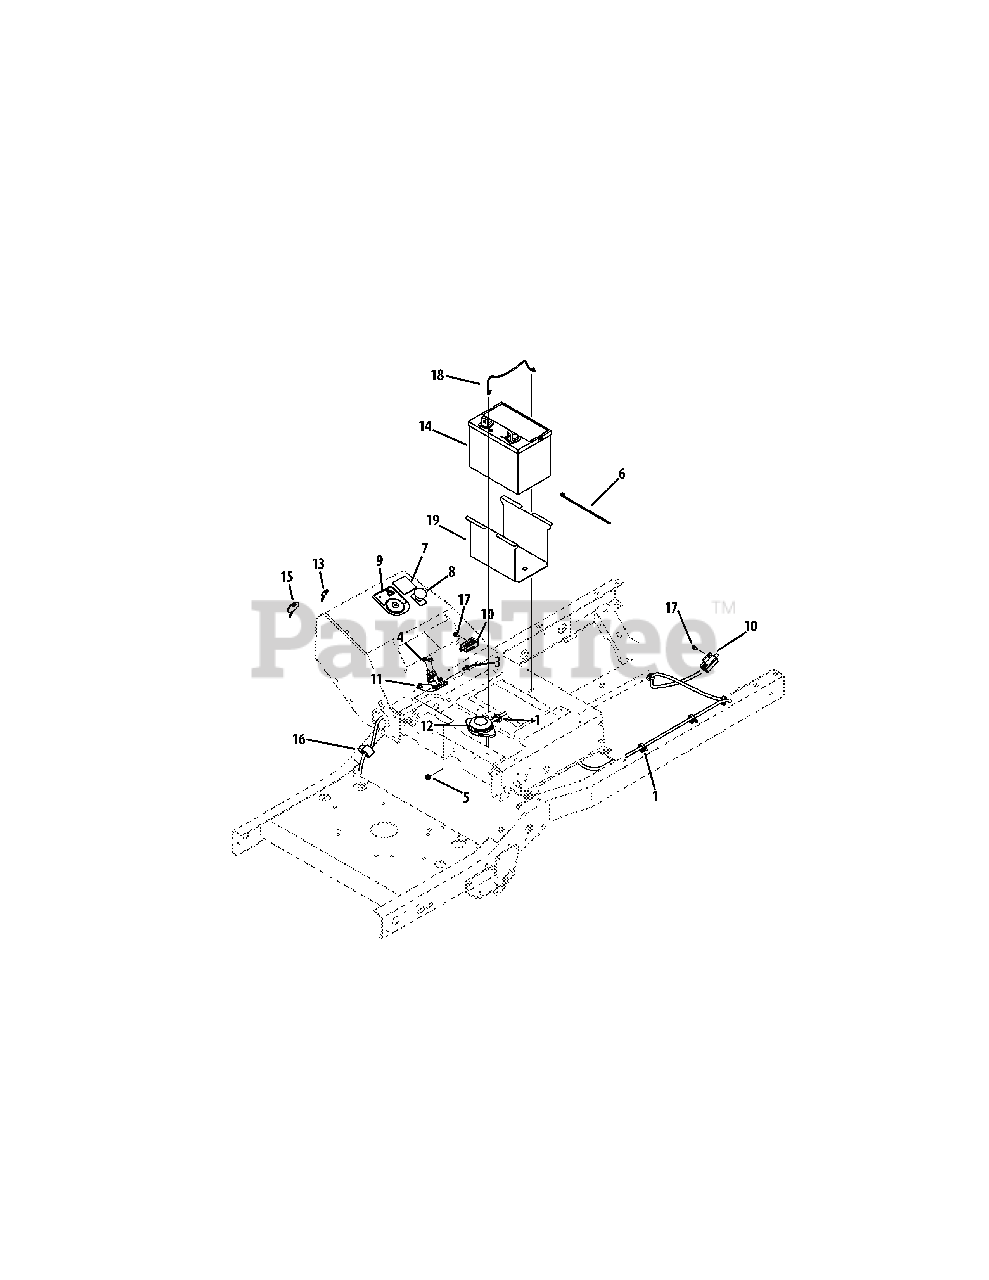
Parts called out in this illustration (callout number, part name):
1	Electrical Conduit Clip, 1/2
3	Hex Washer Screw, 1/4-20 x 0.500
4	Sems Nut, 1/4-20
5	Flange Lock Nut, 1/4-20
6	Cable Tie, 3/16 x .05 x 7.4
7	Hour Meter/Service Minder
8	Electric PTO Switch
9	Key Switch
10	Interlock Switch
11	Solenoid
12	Seat Switch
13	Universal Key Switch
15	Key
16	Clamp, 1.0
17	Shoulder Screw, #10-32 x .500
18	Battery Rod
